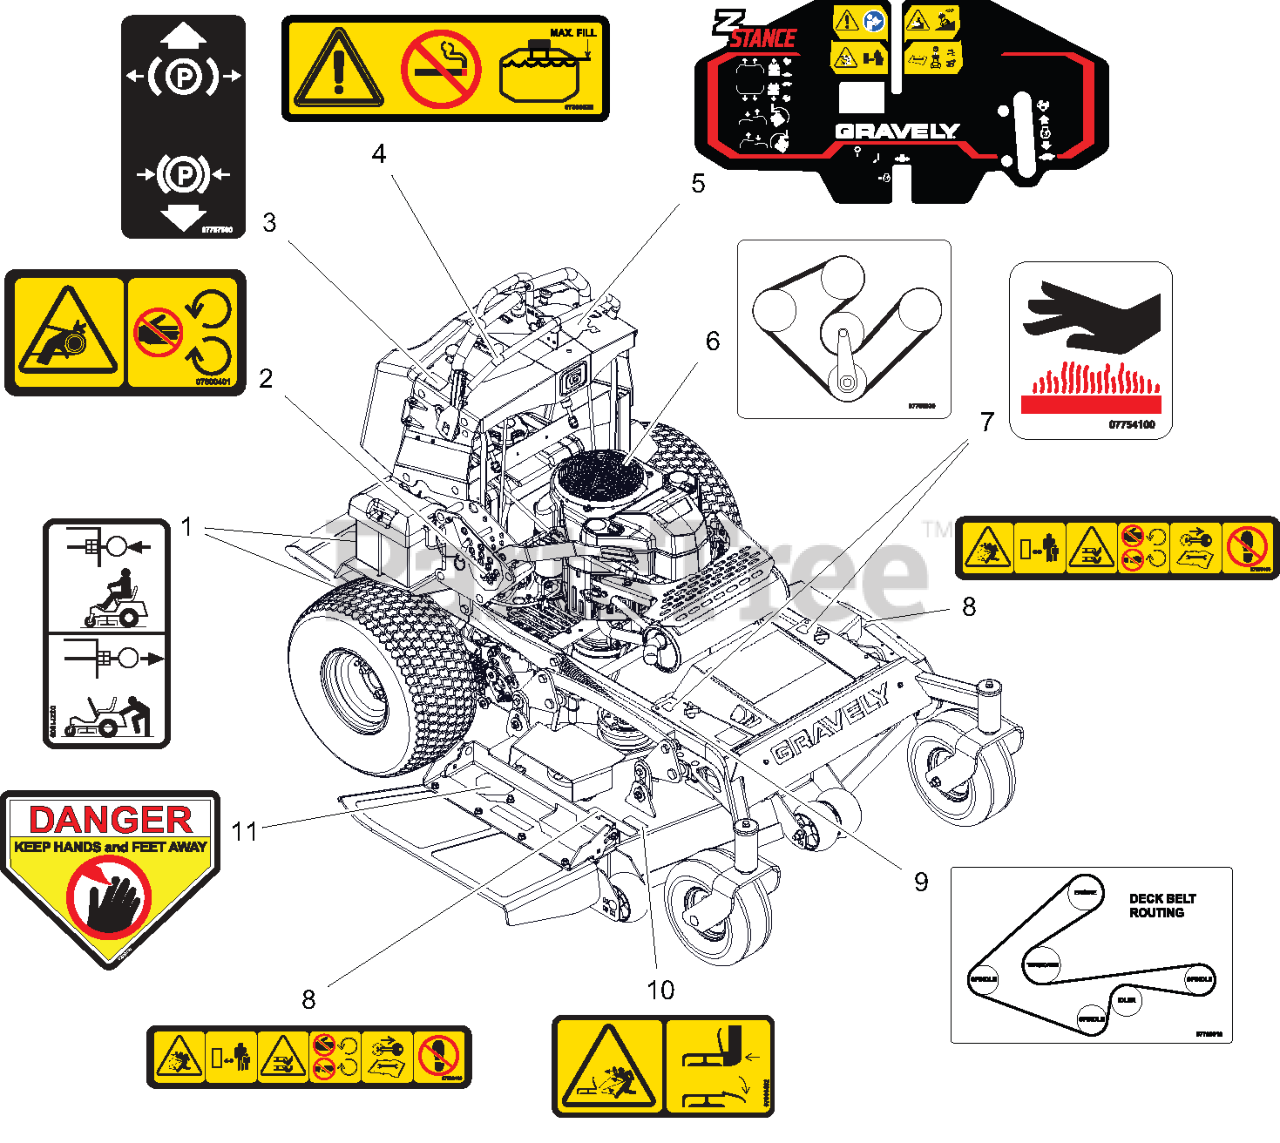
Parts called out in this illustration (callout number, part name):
1	DECAL, TRANSMISSION DISCONNECT
2	DECAL, SAFETY - GUARDING
3	DECAL, PARKING BRAKE LEVER
4	DECAL, FUEL WARNING
5	DECAL- DASH - Z STANCE
6	DECAL, PROSTANCE HYD BELT ROUT
7	DECAL, HOT SURFACE
8	DECAL, DECK SAFETY
9	DECAL, BELT ROUTING 48/52
10	DECAL, SAFETY - DECK GUARDING
11	DECAL, DANGER
